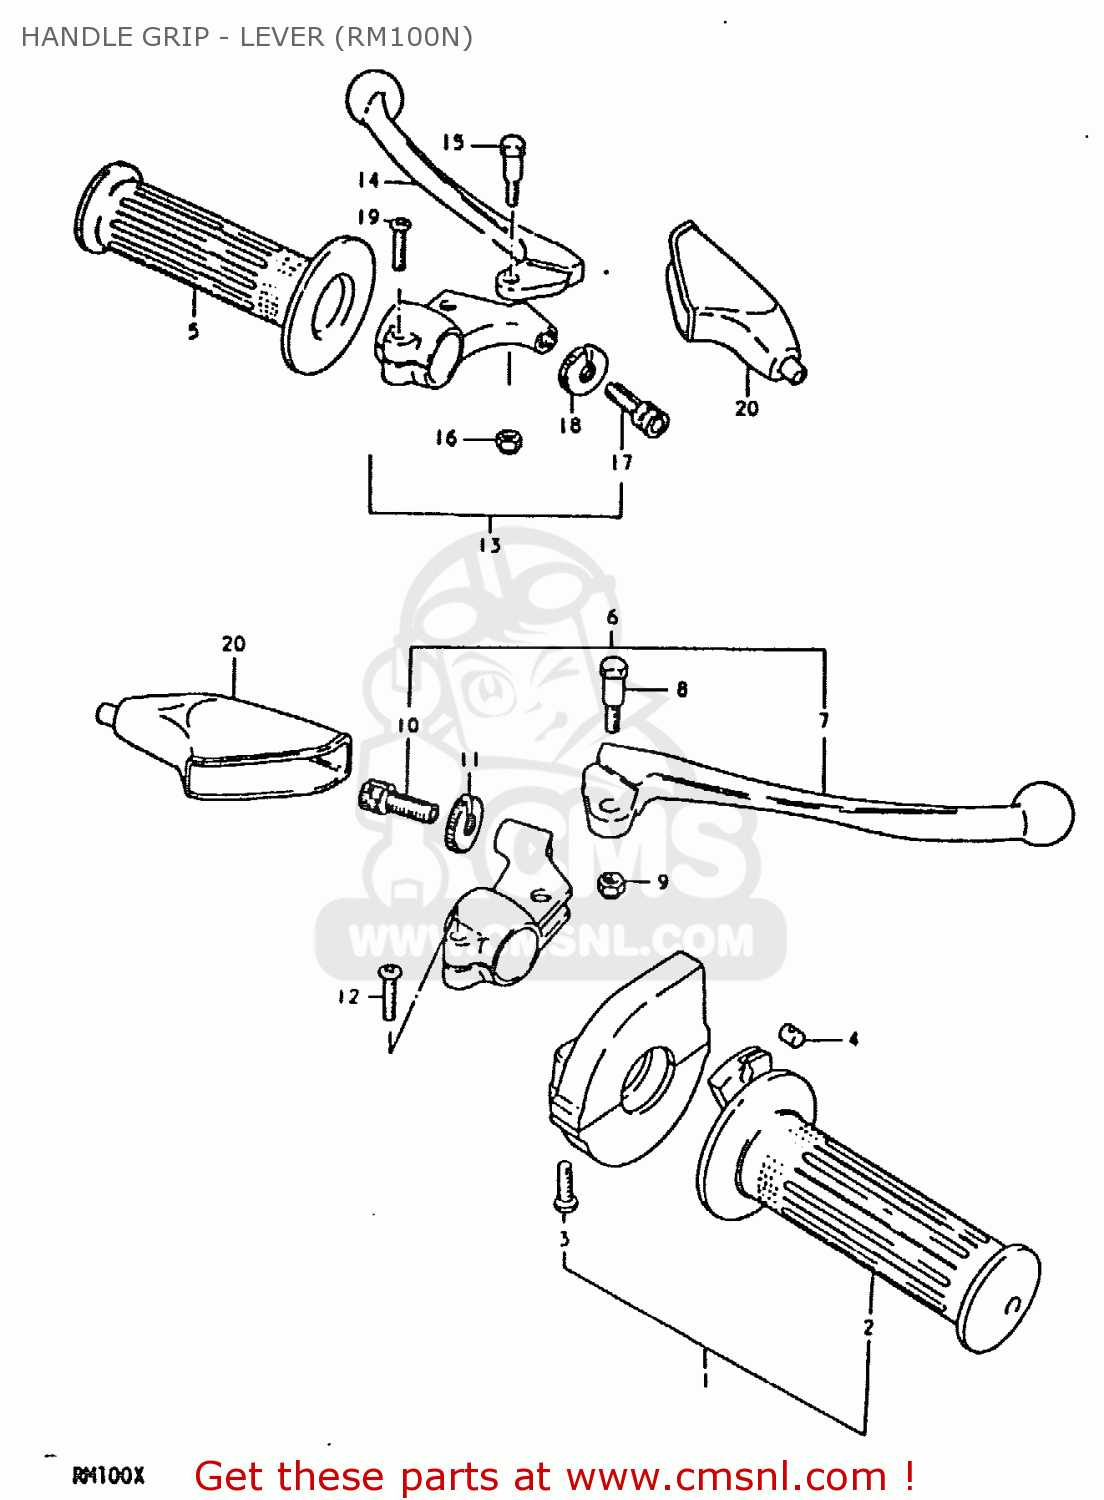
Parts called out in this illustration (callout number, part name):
1	GRIP ASSY,THROTTLE
2	GRIP,THROTTLE
3	SCREW
4	PIECE,THROTTLE END
5	GRIP,LEFT
6	LEVER ASSEMBLY,BRAKE
7	LEVER,BRAKE
8	BOLT,LEVER
9	NUT 6MM
10	ADJUSTER,CABLE
11	NUT,CABLE ADJUSTER
12	SCREW
13	LEVER ASSY,CLUTCH
14	LEVER,CLUTCH
15	BOLT,LEVER
16	NUT 6MM
17	ADJUSTER,CABLE
18	NUT,CABLE ADJUSTER
19	SCREW
20	COVER,CLUTCH LEVER
